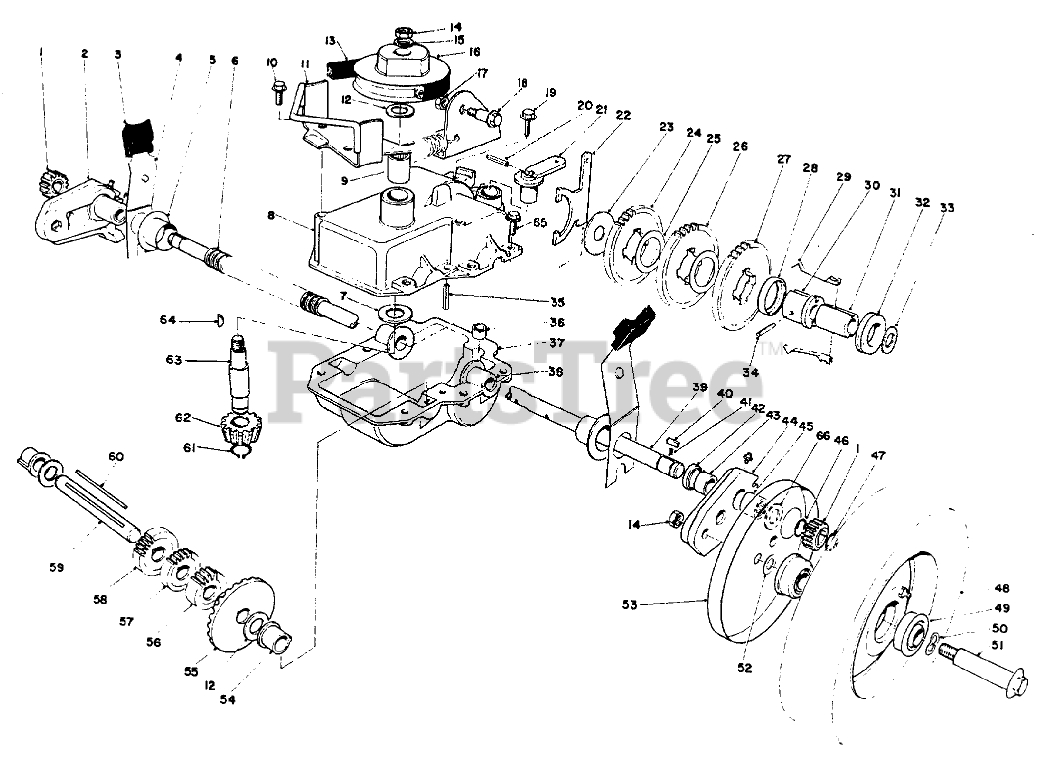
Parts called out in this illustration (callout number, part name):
1	GEAR-PINION
2	Pivot Arm R.H. (Incl. Ref. #42, 43 & 45)
3	KNOB-ARM
4	Spring Arm
5	CAP-END
6	CONDUIT-CONVOLUTED, SPLIT
7	Thrust Washer
8	Case-Upper
9	Bearing
10	Screw
11	Belt Guide Bracket
12	WASHER-THRUST
13	V-BELT
14	Nut
15	WASHER-FLAT
16	PULLEY
17	NUT-LOCK
18	Shoulder Bolt
19	SCREW-HWHTF
20	PIN-COIL
21	LEVER-SHIFT
22	Shift Yoke
23	WASHER
24	GEAR-38T
25	WASHER
26	Gear-40 Tooth
27	GEAR-42T
28	KEY RETAINER
29	Key
30	Body-Sleeve
31	SLEEVE
32	COLLAR-SHIFT
33	WASHER-PLAIN
34	PIN-SPRING
35	ROLL PIN 3/16 X 1 IN
36	BUSHING-YOKE
37	LOWER GEAR CASE CAST
38	Bushing
39	Output Shaft
40	KEY RECTANGULAR
41	SPRING-COMPRESSION
42	Seal
43	Bushing
44	Pivot Arm L.H. (Incl. Ref. #42, 43 & 45)
45	Needle Baring
46	RING-EXT GRIP
47	RING-RETAINING
48	Wheel & Tire Assembly (Incl. Ref. #49)
49	BEARING-BALL
50	SPRING WASHER
51	WHEEL BOLT
52	WASHER
53	Cover-Wheel
54	Botching Shaft
55	BEVEL GEAR
56	14 T GEAR
57	16 T GEAR
58	GEAR-18T
59	Sort Shaft
60	Key Square
61	RING-RETAINING
62	PINION-BEVEL
63	INPUT SHAFT
64	KEY-WOODRUFF
65	SCREW-HWH, THREAD ROLL
66	Washer
